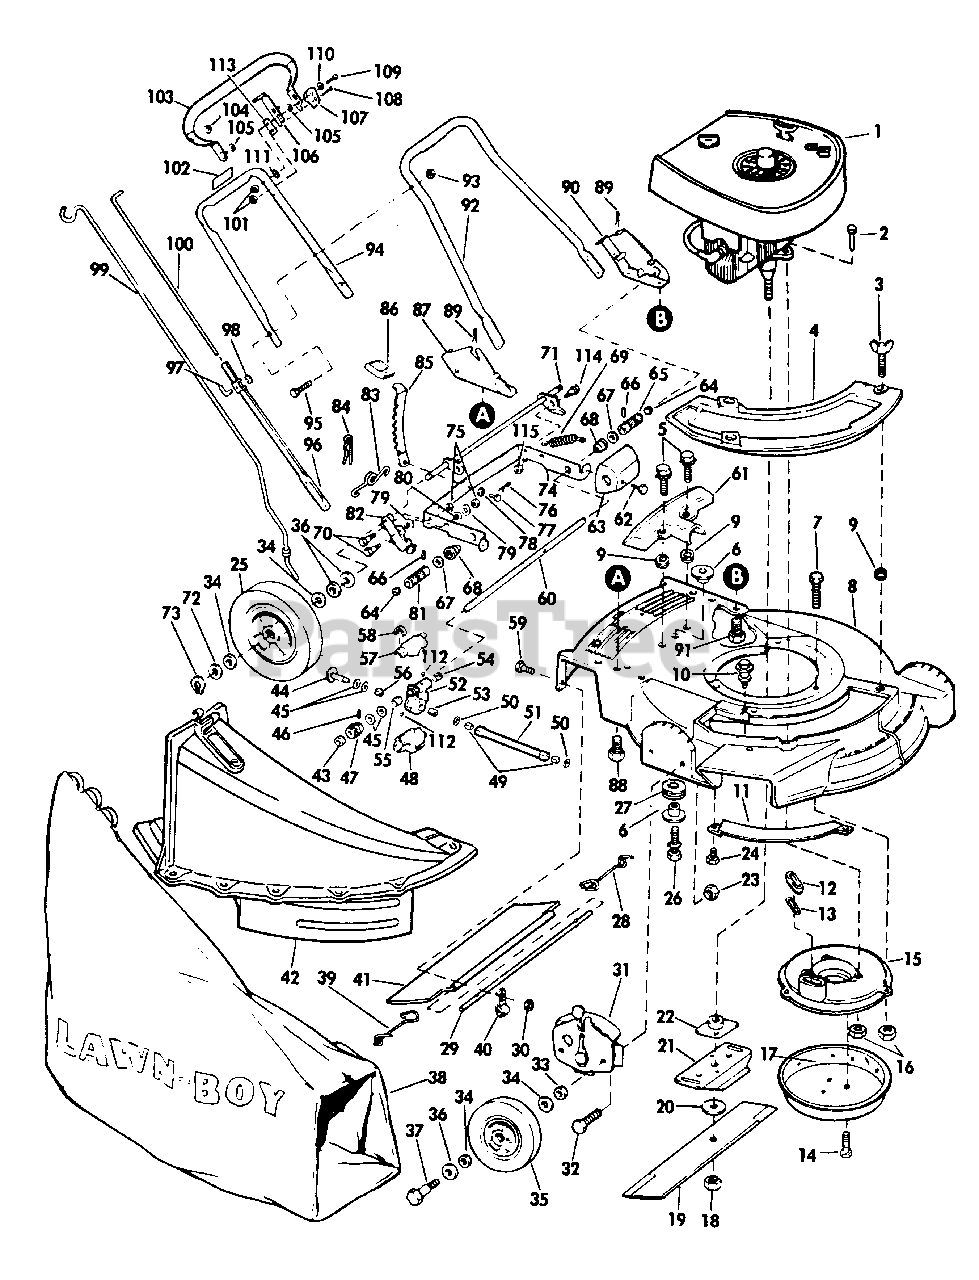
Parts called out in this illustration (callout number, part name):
2	Screw-Crankcase to Muffler Plate
3	Wing Screw
4	Cover Plate
5	Sems Screw-Drive Cover Mounting
6	Spacer-Flanged
7	Screw-Muffler Plate to Housing
8	Housing-21"
9	Grommet
10	Screw
11	Toe Bar
12	Sleeve-Muffler Gasket
13	Gasket-Exhaust
14	Screw-Muffler to Muffler Plate
15	Muffler Plate
16	Nut
17	Muffler Cover
18	Nut-Blade
19	Blade
20	Washer-Blade
21	Stiffener-Blade
22	Collar & Plate Assembly
23	Nut
24	Screw
25	Wheel-Rear
26	Sems Screw
27	Grommet
28	Spring-L.H.
29	Rod
30	Nut
31	Height Adjustment Assembly
32	Screw
33	Washer
34	Washer-Felt
35	Front Wheel
36	Washer (See Note #1)
37	Screw
38	Grass Bag
39	Spring-R.H.
40	Clamp
41	Shield Trailing
42	Chute Assembly
43	Washer-Felt
44	Gear-Driver
45	Washer-Thrust
46	Roll Pin
47	Gear-Drive
48	Cover-Gear Bottom
49	Bushing
50	"O" Ring
51	Tube
52	Bracket & Bearing Assembly
53	Needle Bearing-Sealed
54	Needle Bearing-Sealed
55	Needle Bearing
56	Needle Bearing
57	Cover-Gear Top
58	Clamp
59	Screw
60	Shaft
61	Cover-Drive
62	Screw
63	Guard-Roller
64	Plug
65	Drive Roller-L.H.
66	Pin-Spirol
67	Washer
68	Sleeve & Bearing Assembly
69	Spring
70	Bolt-Shoulder
71	Axle Assembly
72	Washer
73	Retaining Ring
74	Bracket
75	Nut
76	Cotter Pin
77	Pin
78	Washer
79	Washer
80	Washer
81	Drive Roller-R.H.
82	Clutch
83	Spring
84	Hairpin
85	Lever
86	Knob
87	Bracket-Handle-R.H.
88	Screw-Handle Bracket
89	Clip
90	Bracket-Handle-L.H.
91	Screw-Handle Bracket
92	Handle-Lower
93	Nut
94	Handle-Center
95	Screw
96	Control Lever Assembly
97	Screw
98	Nut
99	Rod-Grass Bag
100	Control Rod
101	Nut
102	Decal
103	Handle & Grip Assembly
104	Palnut
105	Washer
106	Lever-Lockout
107	Guard
108	Screw-Stop
109	Bolt-Shoulder
110	Bow Washer
111	Washer
112	Fitting-Grease
113	Stop-Handle
114	Bolt-Shoulder
115	Nut-Lock
